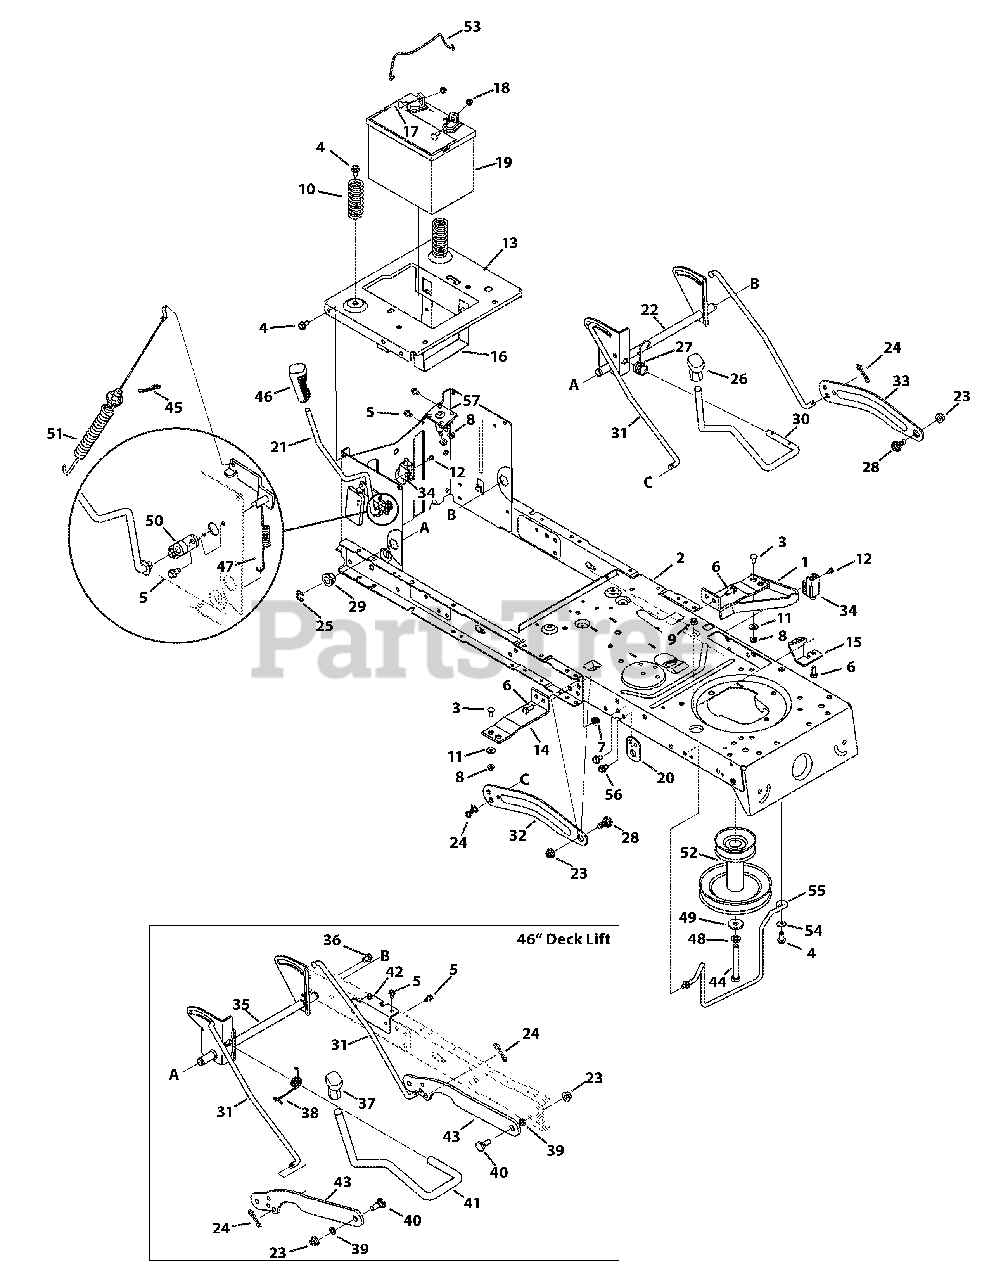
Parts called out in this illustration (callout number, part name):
1	Support Bracket
2	Frame Assembly
3	Screw Carriage, 1/4-20 x .62
4	Screw 5/16-18 x .750
5	Screw, 1/4-20 x .500
6	Hex Screw, 5/16-18 x .75
7	Flangelock Nut, 5/16-18
8	Flangelock Nut, 1/4-20
9	Hexlock Nut, 5/16-18
10	Compression Spacer, 1.28 x 3.125
11	Flat Washer, .28 x .74 x .063
12	Shoulder Spacer, 10-32 x .500
13	Seat Frame Bracket
14	Running Board Bracket
15	Support Frame Bracket
16	Battery Bracket
17	Hex Head Flange, 1/4-20 x .75
18	Sems Nut, 1/4-20
19	230 CCA Battery
20	Support Bracket
21	PTO Handle Assembly
22	Lift Assembly, 38/42"
23	Flangelock Nut, 3/8-16
24	Bow-tie Cotter Pin
26	Handle Grip, 1/2
27	Torsion Spring
28	Shoulder Bolt, 3/8-16 x .625 x .175
29	Hex Flange Bearing
30	Deck Lift Handle
32	38/42" Lift Arm, RH
33	38/42" Lift Arm, LH
34	Switch Interlock
35	Lift Assembly, 46"
36	Screw, 5/16-18 x .625
37	Handle Grip, 5/8
38	Torsion Spring Handle, 46"
39	Flat Washer, .385 x .62 x .063
40	Shoulder Bolt, 3/8-16 x .500 x .270
41	46" Lift Handle
42	Frame Brace Bracket
43	Lift Deck Link
44	Hex Screw, 7/16-20 x 2.75, 46"
44	Hex Screw, 7/16-20 x 3.25, 38/42"
45	Click Pin, .092 x 1.64
46	Handle Grip, 3/8
47	PTO Spring Extension
48	Regular Duty Washer Lock, 7/16
49	Flat Washer, .450 x 1.250 x .164
50	PTO Bearing
51	Deck Engage Cable
52	Engine Pulley, 3.39 x 6.12, 46"
52	Engine Pulley, 3.39 x 6.12, 38/42"
53	Battery Hold Down Rod
54	Flat Washer, .406 x .875 x .059
55	42" Belt Keeper
55	46" Belt Keeper
56	Screw, 5/16-18.0 x .625
57	12V Solenoid
